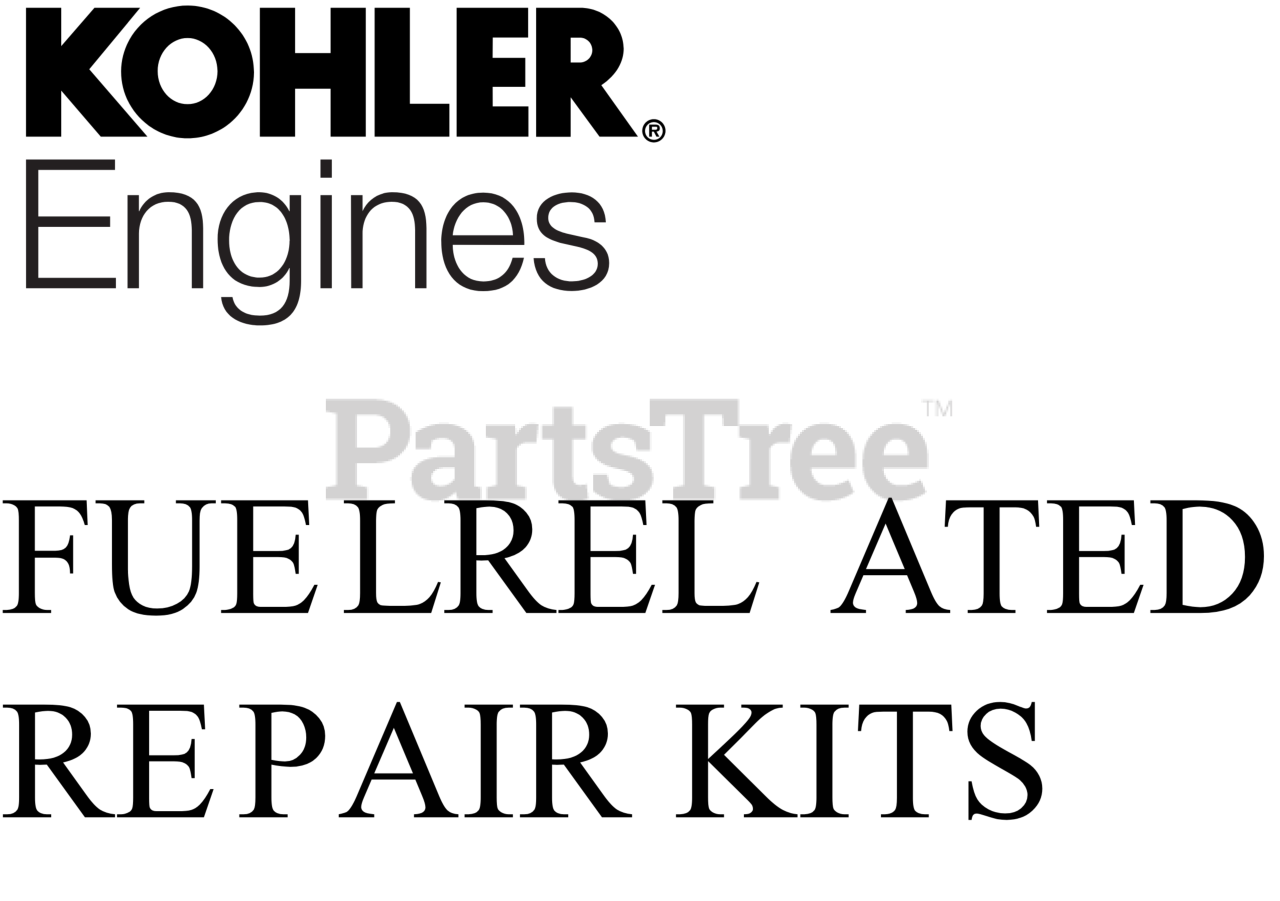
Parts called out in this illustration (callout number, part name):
NI	KIT, HIGH ALTITUDE (4,000-8,000 FT)
NI	KIT, HIGH ALTITUDE (ABOVE 8,000 FT.)
NI	KIT, CARBURETOR REPAIR
NI	KIT, CARBURETOR COMPLETE
